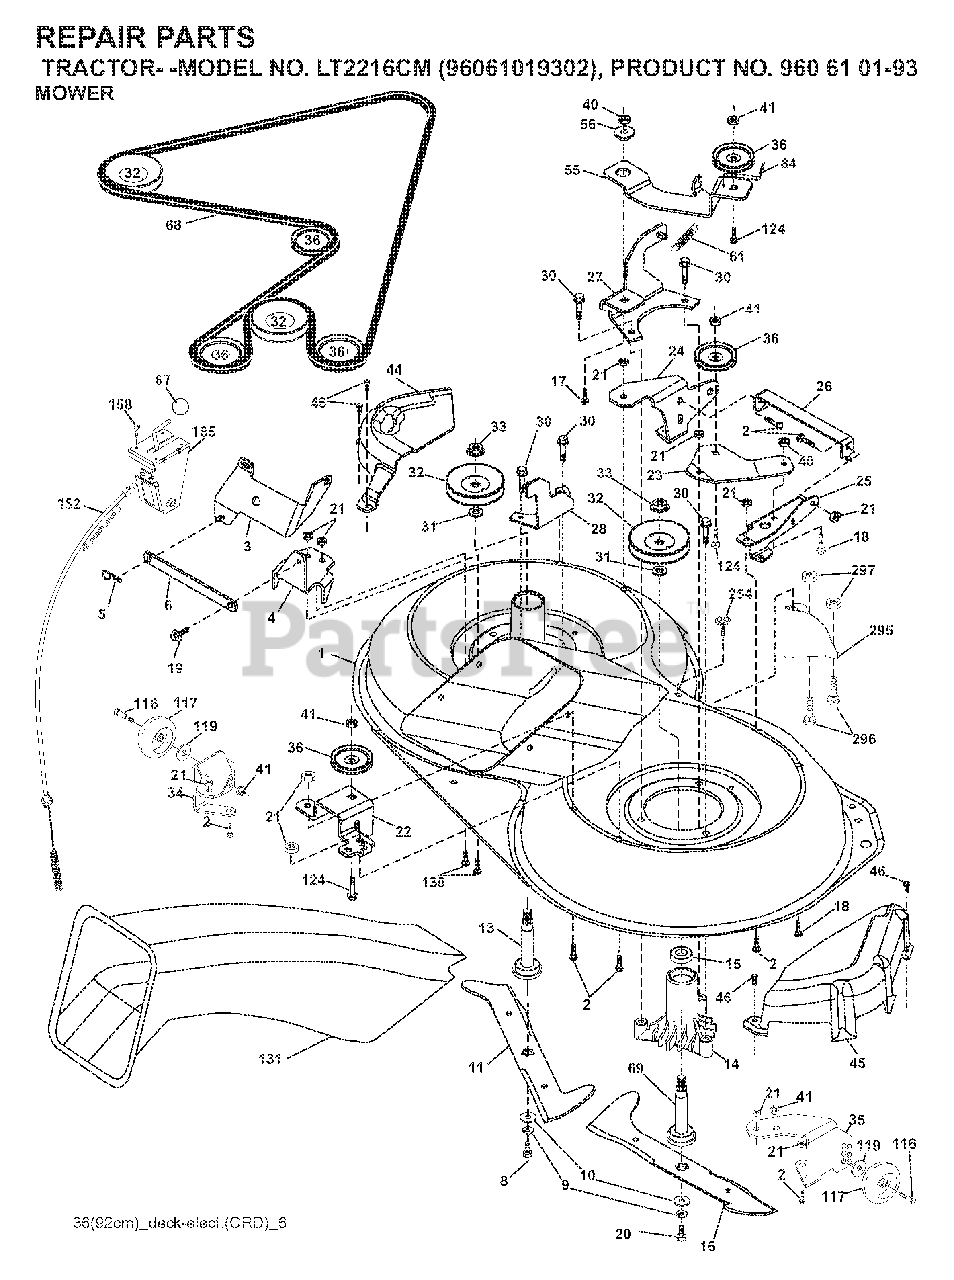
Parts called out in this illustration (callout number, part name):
2	BOLT
3	BRACKET
5	RETAINER-SPRNG RB
6	BAR SWAY
9	LOCKWASHER
10	WASHER.BLADE
13	SHAFT ASM VENT
14	HSG MANDREL
17	BOLT.3/8-14X1.25
19	BOLT SHD 5/16-18
21	LOCKNUT
24	BRACKET
25	BRACKET
28	BRACKET
30	SCREW, WASHER HEAD
31	WASHER.SPACER.MANDREL
32	PULLEY MANDREL
33	NUT.FLANGE.LOCK.TOP
36	PULLEY.IDLER.4.25
40	LOCKNUT
41	NUT LOCK FLG 3/8-16 UNC
45	MANDREL COVER
46	SCREW.1/4-20X5/8
56	SPACER.RETAINER.MOWER
67	KNOB T (3/8 HOLE)
69	SHAFT.ASM.W/LWR.BRG.RH.THREAD
84	KEEPER, BELT IDLER
116	BOLT.SHOULDER.3/8-16X3-5/8
117	WHEEL. GUAGE RALLY
118	NUT LOCK FLG 3/8-16 UNC
124	BOLT.3/8-16X1.50
131	CHUTE BAGGER
158	SCREW
185	HEAD ASM. CABLE CLUTCH
254	SCREW 3/8-16X1
296	BOLT
297	NUT CENTERLOCK
